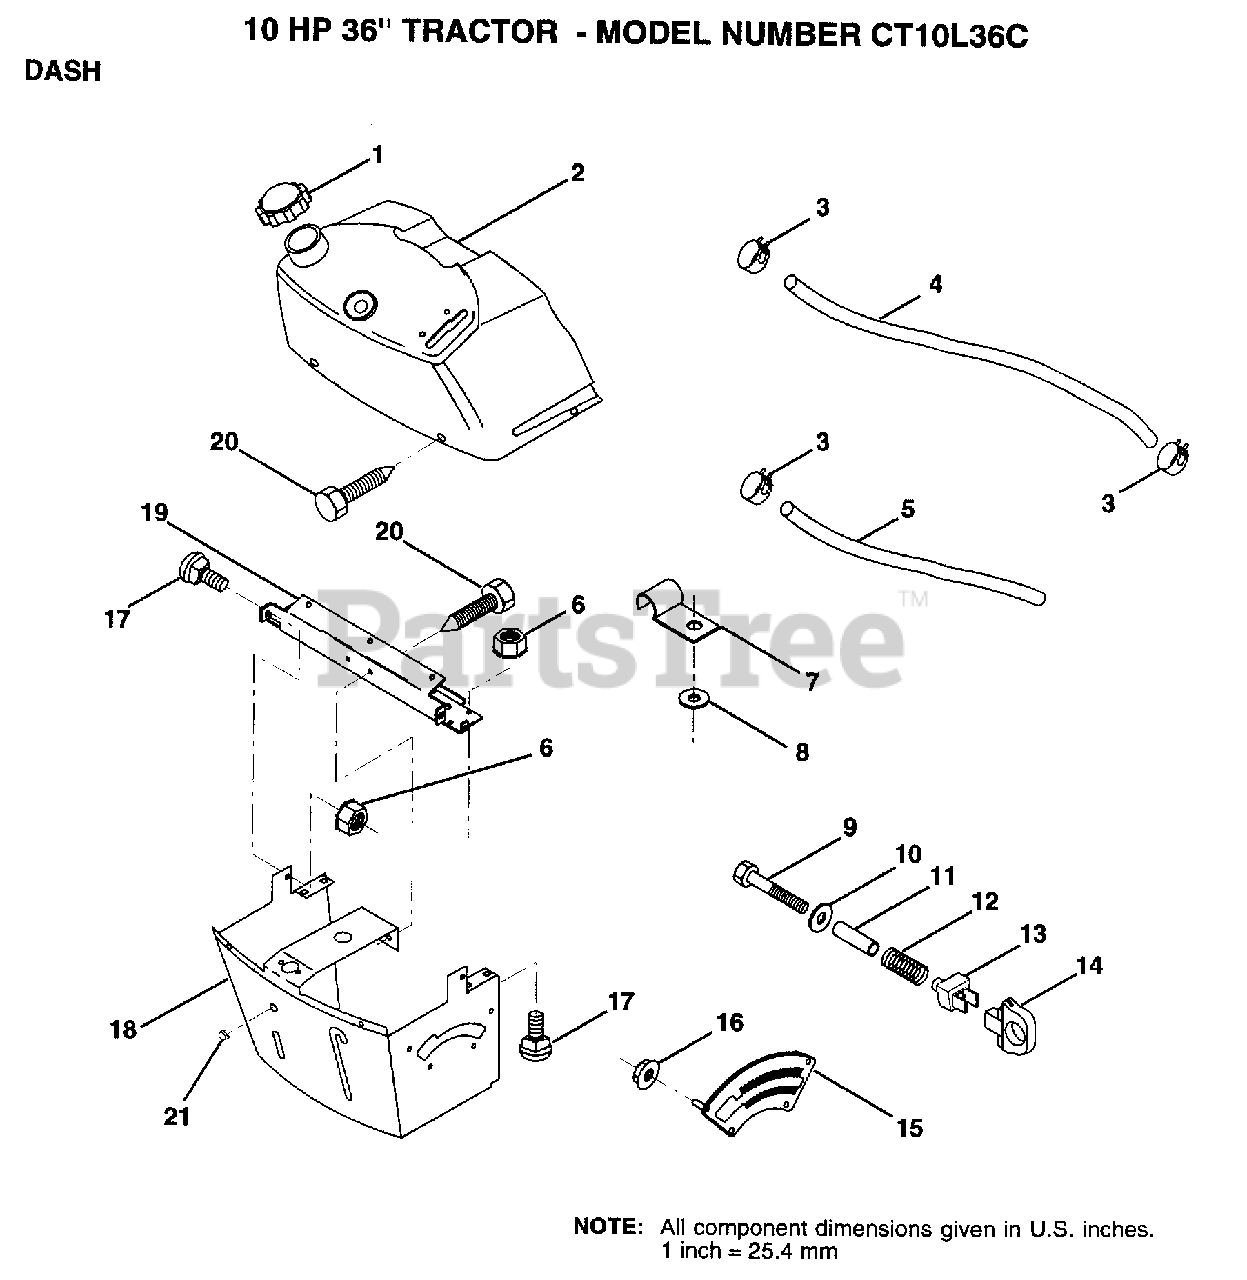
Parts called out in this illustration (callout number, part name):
1	CAP BLK FUEL LR
2	TANK.ASM.DASH.LR
3	HOSE CLAMP
5	FUEL LINE T
6	NUT
7	CLIP T
8	WASHER PM
9	BOLT
11	SPACER SPLIT
12	SPRING M
13	"KNOB,HGT RETAINER"
14	KNOB
15	ADJUSTER QUAD
16	NUT
17	BOLT
18	SUPT ASSY DASH
19	CROSS BRACE
20	SCREW.1/4-20X1/2
21	PLUG DOME
